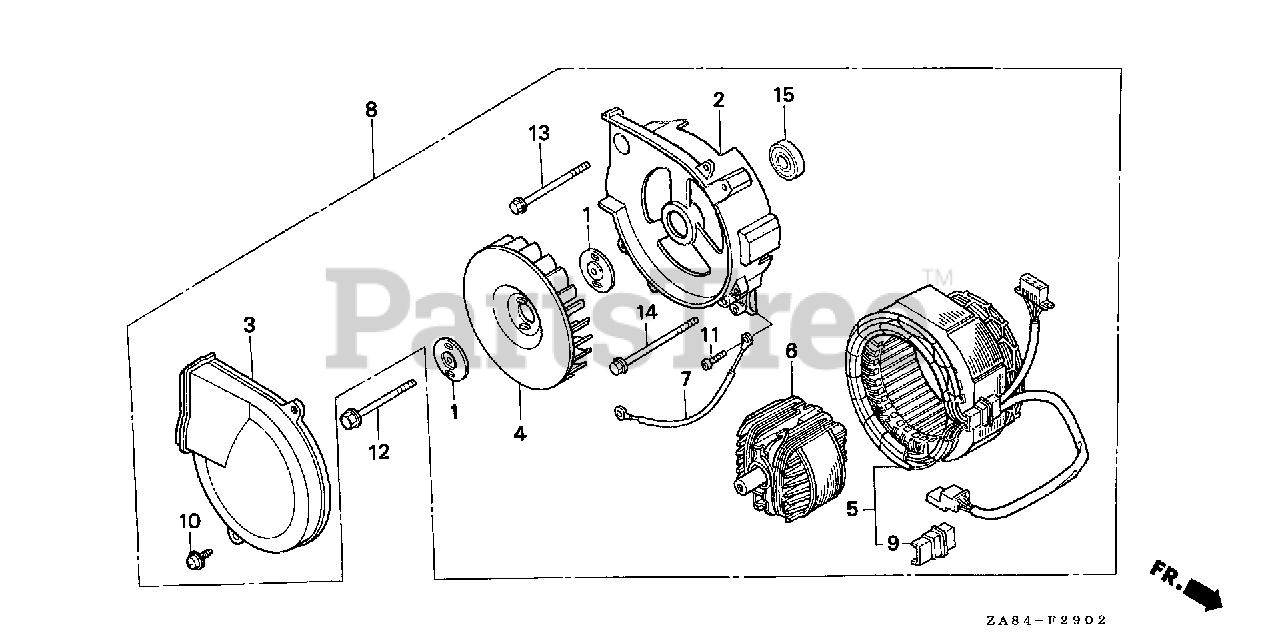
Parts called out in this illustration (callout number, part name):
1	PLATE, FAN SETTING
2	ROTOR SET
2	HOUSING, RR.
3	COVER, GENERATOR FAN
4	FAN, COOLING
5	STATOR ASSY.
6	ROTOR
7	WIRE, GROUND
8	GENERATOR ASSY. (EM-A)
8	GENERATOR ASSY. (EM-SA)
10	SCREW, TAPPING (5X12)
11	SCREW, PAN (5X12)
12	BOLT, FLANGE (8X92)
13	BOLT, FLANGE (6X75)
14	BOLT, FLANGE (6X95)
15	BEARING ASSY. (6002)
15	BEARING, RADIAL BALL (6002)
